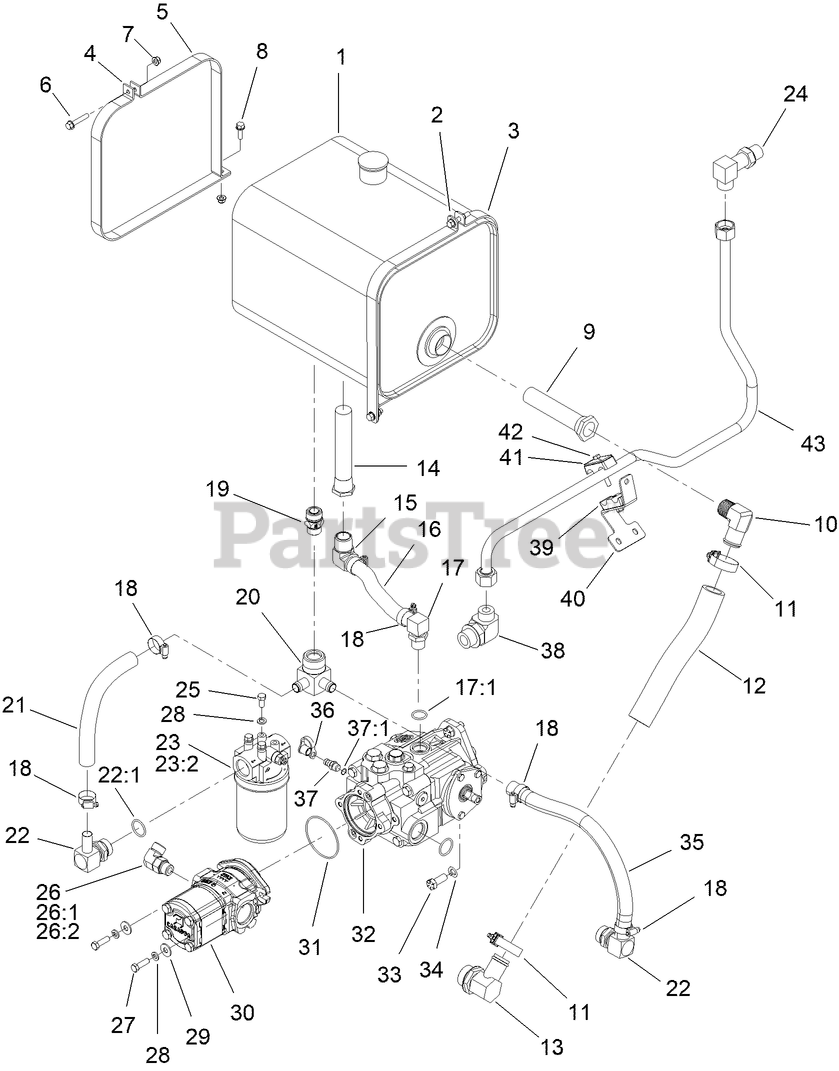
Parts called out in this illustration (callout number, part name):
2	STRAP-TANK
3	STRAP-TANK, HYDRAULIC
4	STRAP-TANK
5	STRAP-TANK
6	SCREW-HWH
7	NUT-HF, NI
8	SCREW-HHF
9	FILTER ASM
10	FITTING-ELBOW, 90
11	CLAMP
12	HOSE SUCTION
13	S/O COUPLER (20S-20H90)
14	FILTER ASM
15	FITTING-ELBOW, 90
16	HOSE LP
17	FITTING-ELBOW, 90
17:1	O-RING
18	CLAMP-HOSE
19	FLOW CHECK VALVE (-12S-120, 5 PSI)
20	S/O COUPLER
21	HOSE RETURN
22	FITTING-ELBOW, 90
22:1	O-RING
23	HYD FILTER ASM
23:2	FILTER-HYD
24	CONNECTOR (12S-12O90, XL)
25	SCREW-HH
26	FITTING-ELBOW, 90 DEG
26:1	O-RING
26:2	O-RING
27	SCREW-HH
28	WASHER-LOCK
29	WASHER
30	PUMP TANDEM (1.29/.44 CIR)
31	O-RING (152 D70)
32	HYD VARIABLE PUMP ASM
33	SCREW-HHF
34	WASHER-LOCK
35	HOSE-RETURN 3/4
36	CAP-DUST
37	FITTING-DIAGNOSTIC
37:1	O-RING
38	CONNECTOR (12O-16S90)
39	CLAMP-TUBE
40	BRACKET-TUBE
41	PLATE-COVER
42	SCREW-HH
43	HARDLINE (-12 COOLER TO FILTER)
